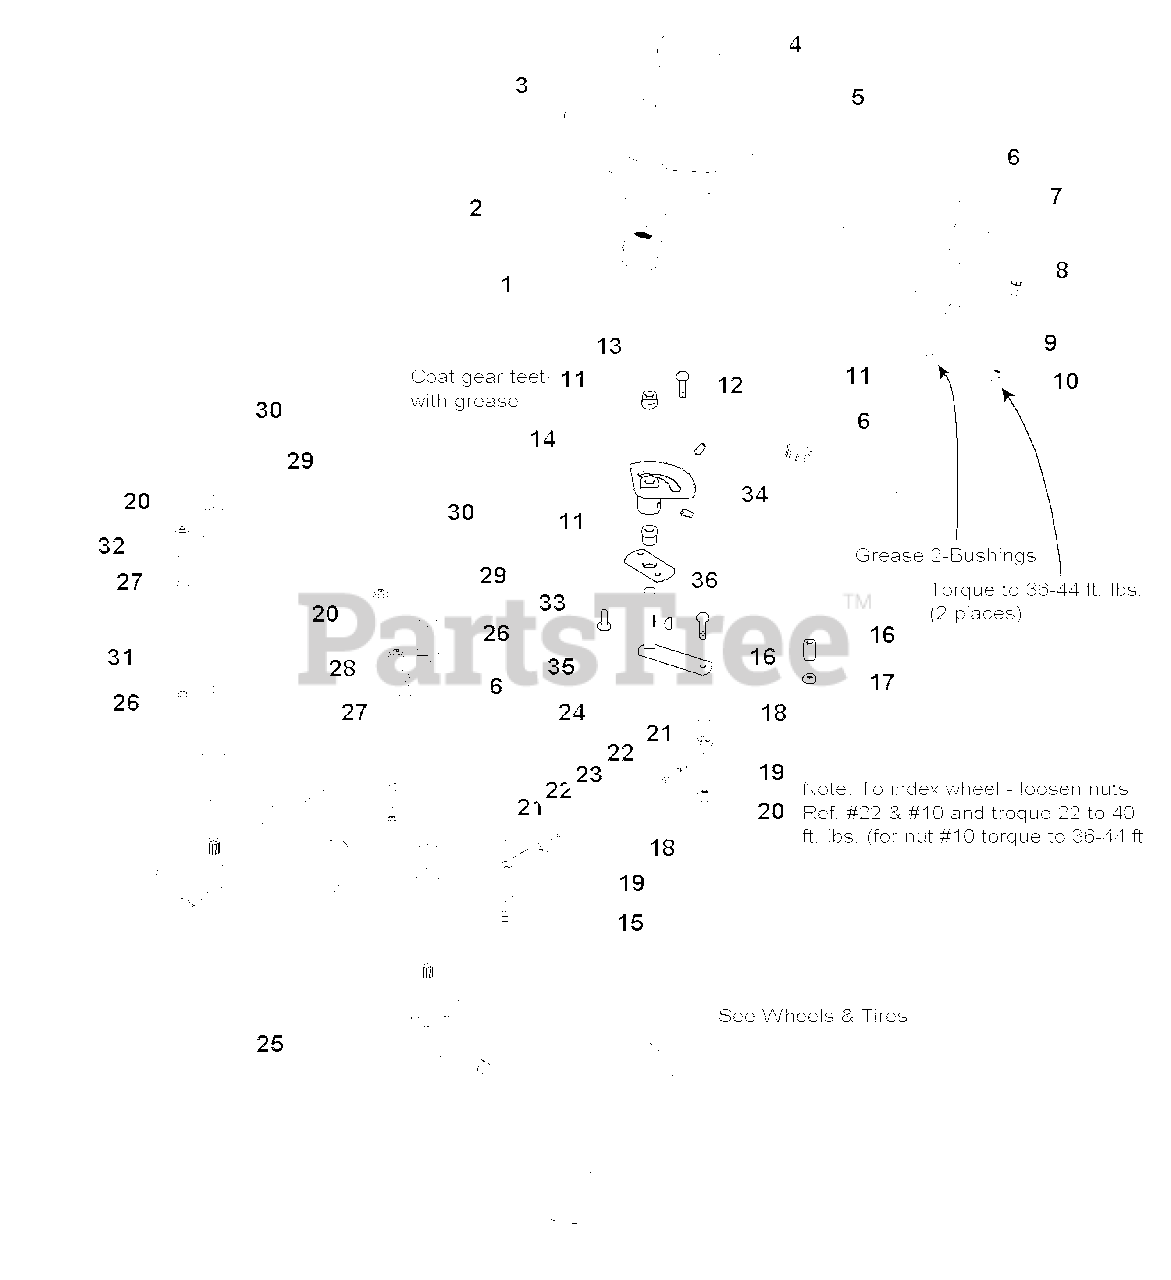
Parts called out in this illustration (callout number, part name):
1	TUBE, Flexible Black Rubber
2	PIN, Spring, 5/16 x 2-1/2
3	WHEEL, Steering
4	CAP, Steering Wheel
5	PIN, Cotter, 3/16 x 1-1/4
6	WASHER, 3/4
7	WASHER, Plain, 1 x 1-1/2 x .07
8	CARRIAGE BOLT, 3/8-16 x 1
9	PLATE, Mounting, Steering
10	NUT, Hex Flange Whizlock, 3/8-16
11	BUSHING, Nylon
12	SHAFT & GEAR ASSEMBLY, Steering
13	CAPSCREW, Hex Head, 5/16-18 x 1-1/2
14	GEAR & HUB ASSEMBLY, Steering
15	CAPSCREW, Hex Head, 3/8-16 x 1-3/8
17	NUT, Hex Lock ESNA Light, 5/16-18
19	WASHER, 3/8
20	NUT, Hex Flange Two-Way Lock, 3/8-16
21	JOINT, Ball
22	NUT, Hex Jam 1/2-20
24	DRAG LINK ASSEMBLY, (Includes Ref. Nos. 21, 22 & 23)
25	SPINDLE ASSEMBLY
26	CAPSCREW, 3/8-16x x1-3/8
28	STEERING ARM ASSEMBLY, L H
30	KLIPRING, 5/8
32	STEERING ARM ASSEMBLY, R H
33	CAPSCREW, Hex Head,Taptite, 5/16-18 x 1
34	SET SCREW, Square Head, 5/16- 18 x 1/2
35	PITMAN ARM ASSEMBLY
36	KEY, Hi-Pro
